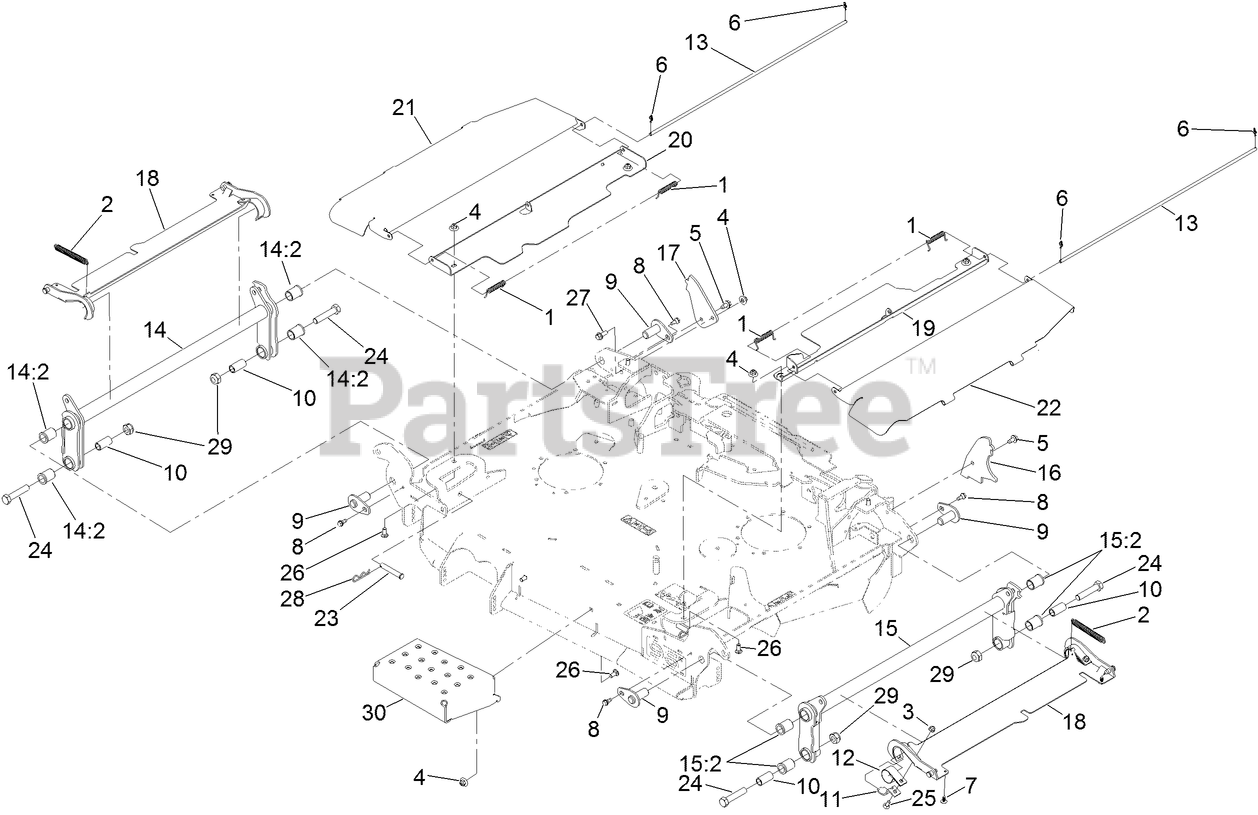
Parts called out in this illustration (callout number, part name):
1	SPRING-TORSION
2	SPRING
3	NUT-HF, NI
4	NUT-FLANGE, NI
5	SCREW-HWH
6	PIN-COTTER, LOCKING
7	PLUG-PLASTIC
8	SCREW-SHOULDER
9	PIN-DECK
10	BUSHING-FLOAT, DECK
11	PLATE-RETAINER, BEARING
12	BEARING-STRAP, NYLON
13	COVER-ROD, PIVOT
14	RH FOLD ARM ASM
14:2	BUSHING-FLANGED
15	LH FOLD ARM ASM
15:2	BUSHING-FLANGED
16	BRACKET-DECK STOP, LH
17	BRACKET-DECK STOP, RH
18	COVER-WING
19	SHIELD-CENTER, LH
20	SHIELD-CENTER, RH
21	PANEL-SHIELD HINGE, RH
22	PANEL-SHIELD HINGE, LH
23	PIN-CLEVIS
24	SCREW-HH
25	SCREW-CARR
26	BOLT-CARR
27	SCREW-HHF
28	PIN-HAIR
29	NUT-LOCK
30	PANEL-STEP
